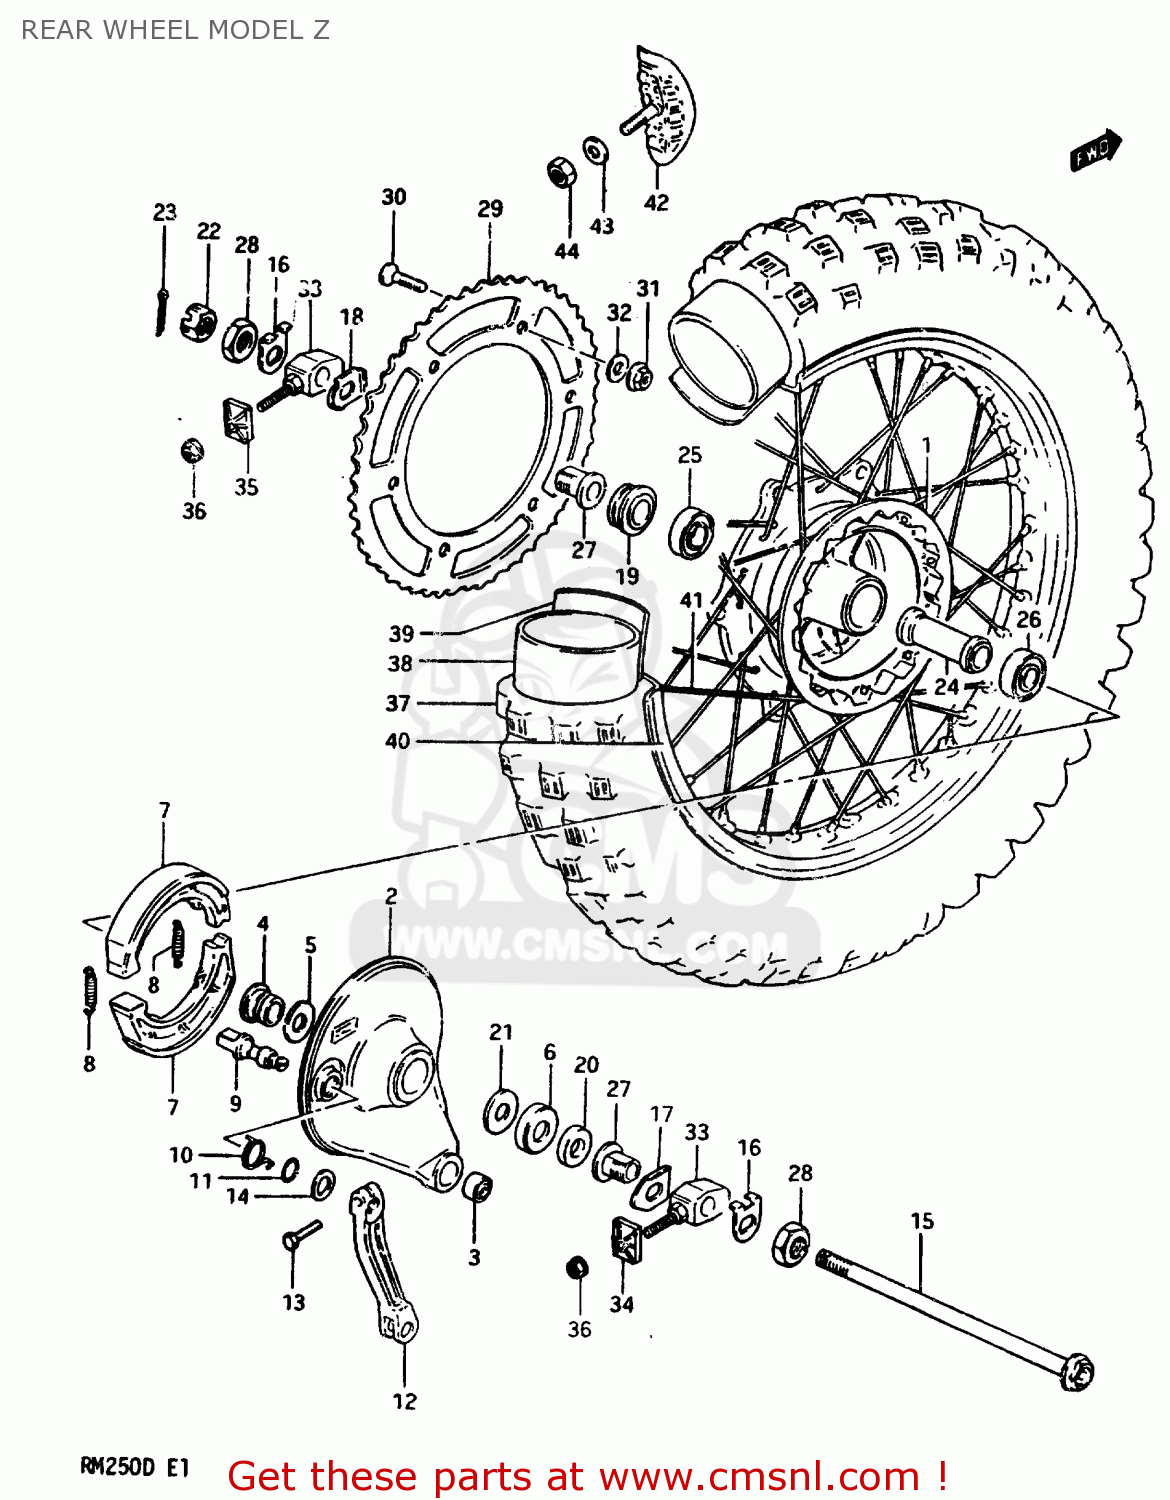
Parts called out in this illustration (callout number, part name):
1	DRUM,REAR HUB
2	PANEL SET,REAR HUB
3	SPHERICAL BRNG,TORQUE LINK
4	SPACER,RR BRAKE ANCHOR PANEL
5	SEAL,OIL(20X27X5)
6	CVR,RR BRAKE AHR PNL DUST SEAL
7	SHOE,BRAKE (MCA)
8	SPRING(L:35.8)
9	CAM,FR BRAKE
10	SPRING
11	O RING(D:2.5,ID:11.4)
12	LEVER,RR BRAKE CAM
13	BOLT
14	WASHER(12.5X20X1)
15	AXLE,REAR
16	WASHER,CHAIN ADJUSTER GUIDE
17	PLATE,CHAIN ADJUSTER,RIGHT
18	PLATE,CHAIN ADJUSTER,LEFT
19	SPACER,RR AXLE,L
20	SPACER,REAR AXLE,RIGHT
21	WASHER,THRUST
22	NUT
23	COTTER PIN
24	SPACER
25	BEARING
26	BEARING
27	SPACER,CHAIN ADJUSTER
28	NUT
29	SPROCKET,REAR
30	SCREW(8X33.5)
31	NUT
32	WASHER
33	ADJUSTER,CHAIN
34	PLATE,CHAIN ADJUSTER GUIDE,R
35	PLATE,CHAIN ADJUSTER GEAR
36	NUT
37	TIRE
38	TUBE,INNER
39	PROTECTOR,WHEEL,INNER
40	RIM,REAR WHEEL (2.15-18)(
41	SPOKE SET,REAR
42	STOPPER,BEAD
43	WASHER
44	NUT
